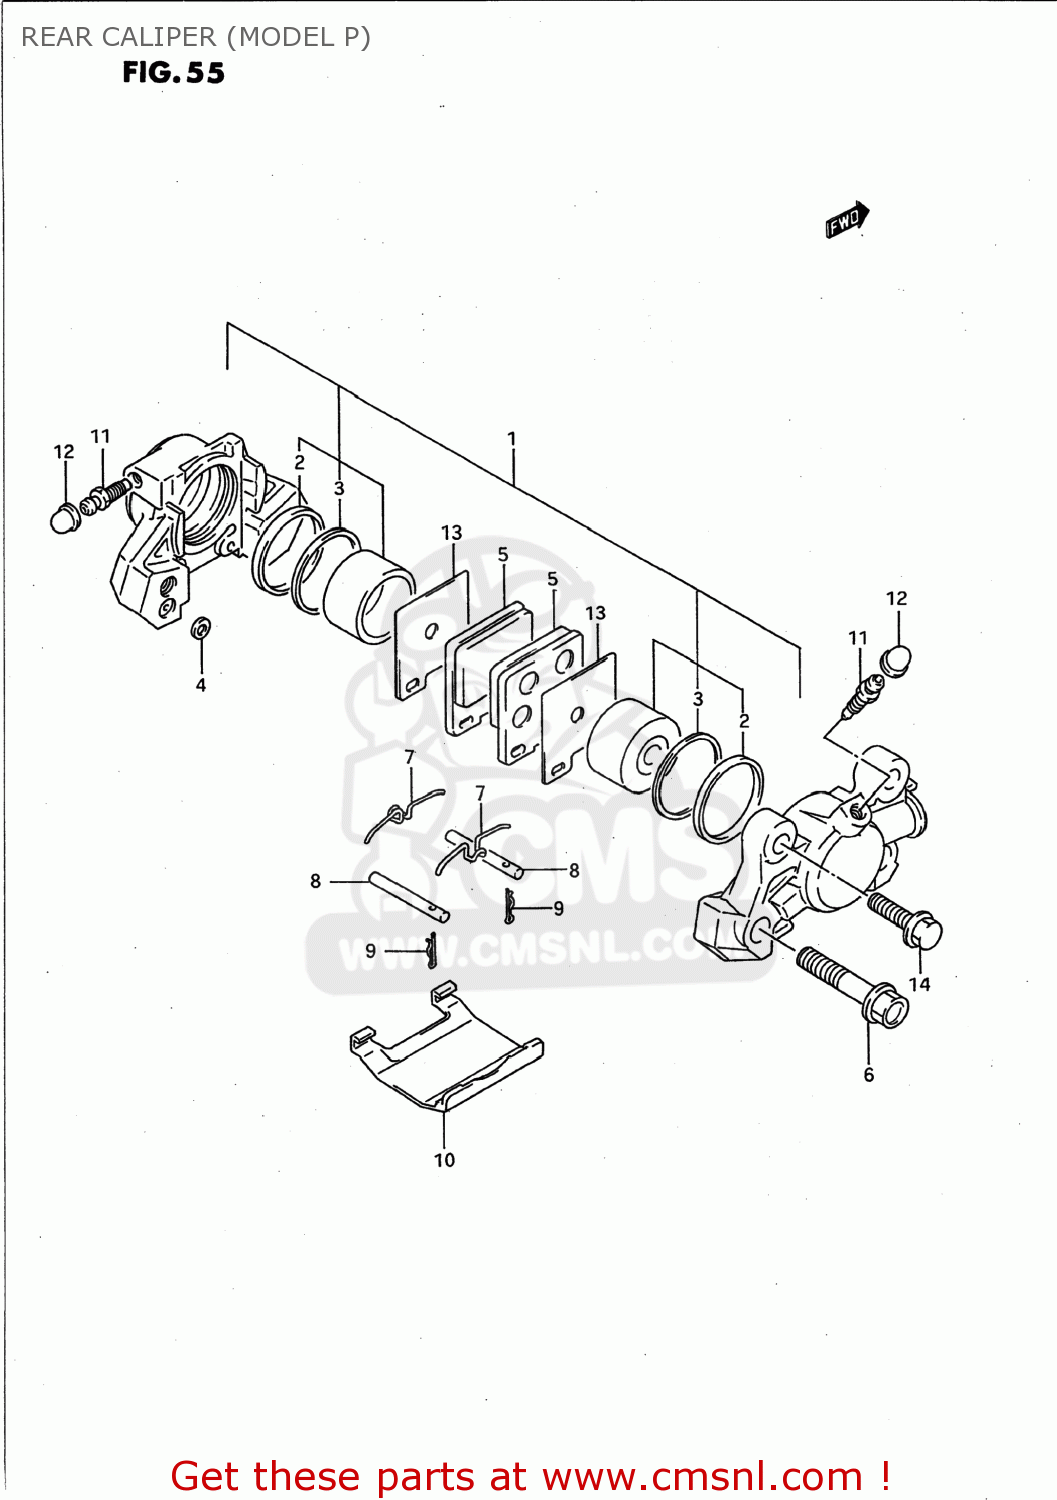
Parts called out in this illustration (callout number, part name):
1	PISTON SET
2	SEAL,PISTON
3	SEAL,WIPER
4	SEAL,JOINT
5	PAD,BRAKE
6	BOLT
7	SPRING
8	PIN,PAD
9	CLIP,PAD PIN
10	COVER
11	BLEEDER
12	CAP,BREATHER
13	SHIM,PAD
14	BOLT
